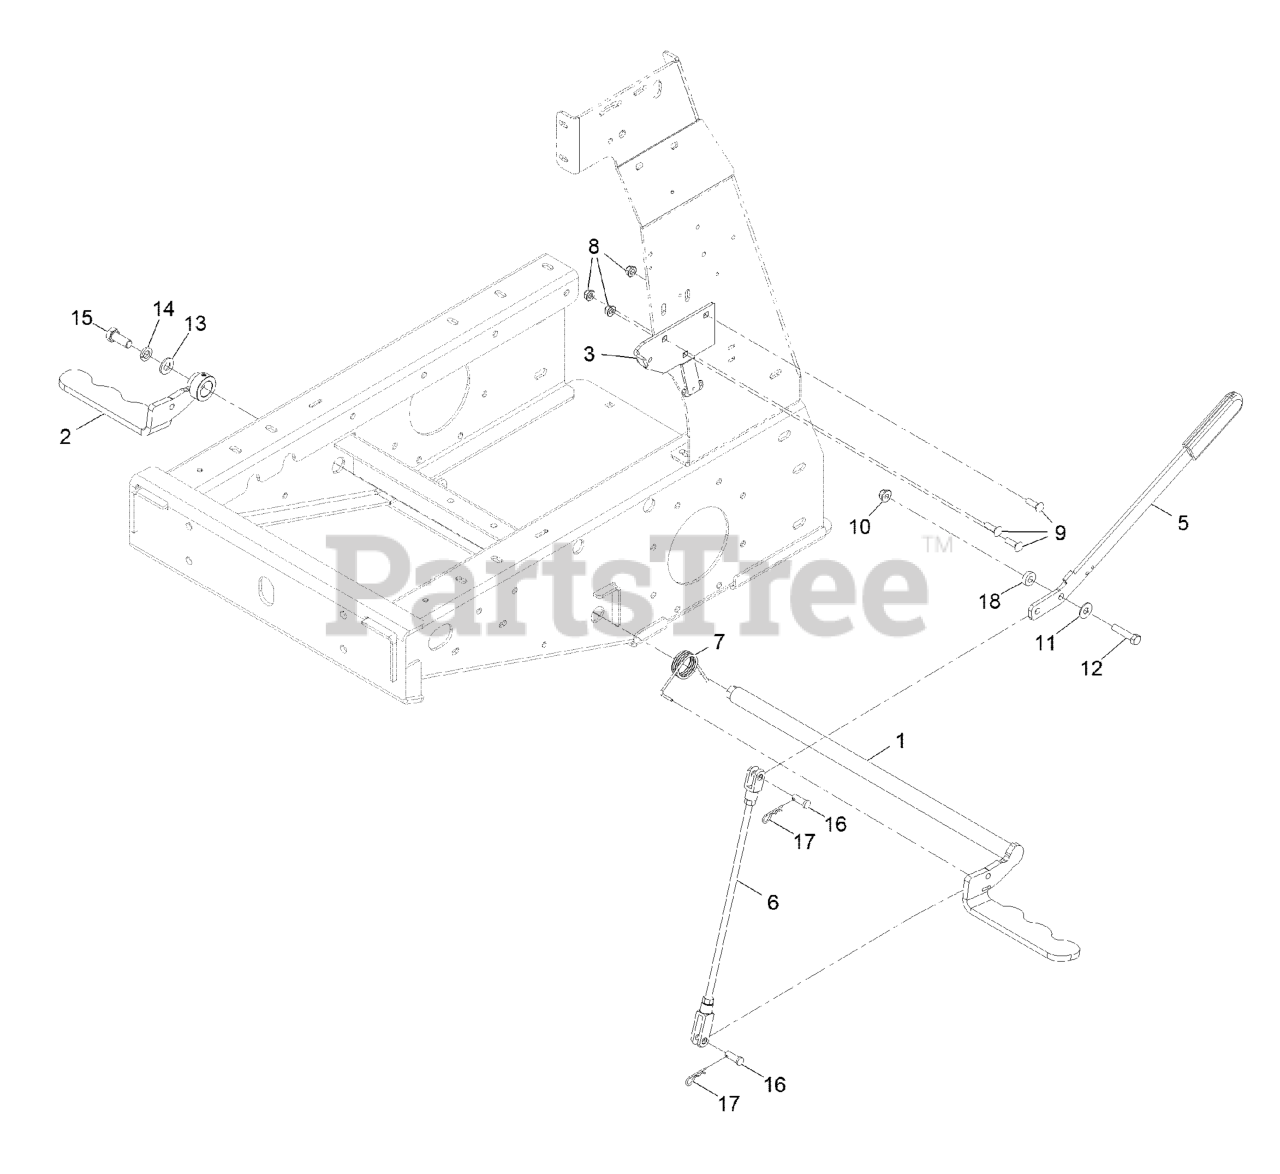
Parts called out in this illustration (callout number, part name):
1	Arm-Brake, Lt [black]
2	Arm-Brake, Rt [black]
3	Bracket-Handle, Brake
5	Handle-Brake
6	ASM, Rod-Brake
7	SPRING-TORSION
8	Nut-Hex Flange
9	Bolt,Carriage,5/16-18X1,ST/ST 18-8
10	NUT-HF, NI
11	WASHER-FLAT
12	SCREW-HH
13	WASHER-FLAT
14	WASHER-LOCK
15	Screw ( .50-20Unfx1.25 Grade 8]
16	PIN-CLEVIS
17	Pin-Hair
18	SPACER
